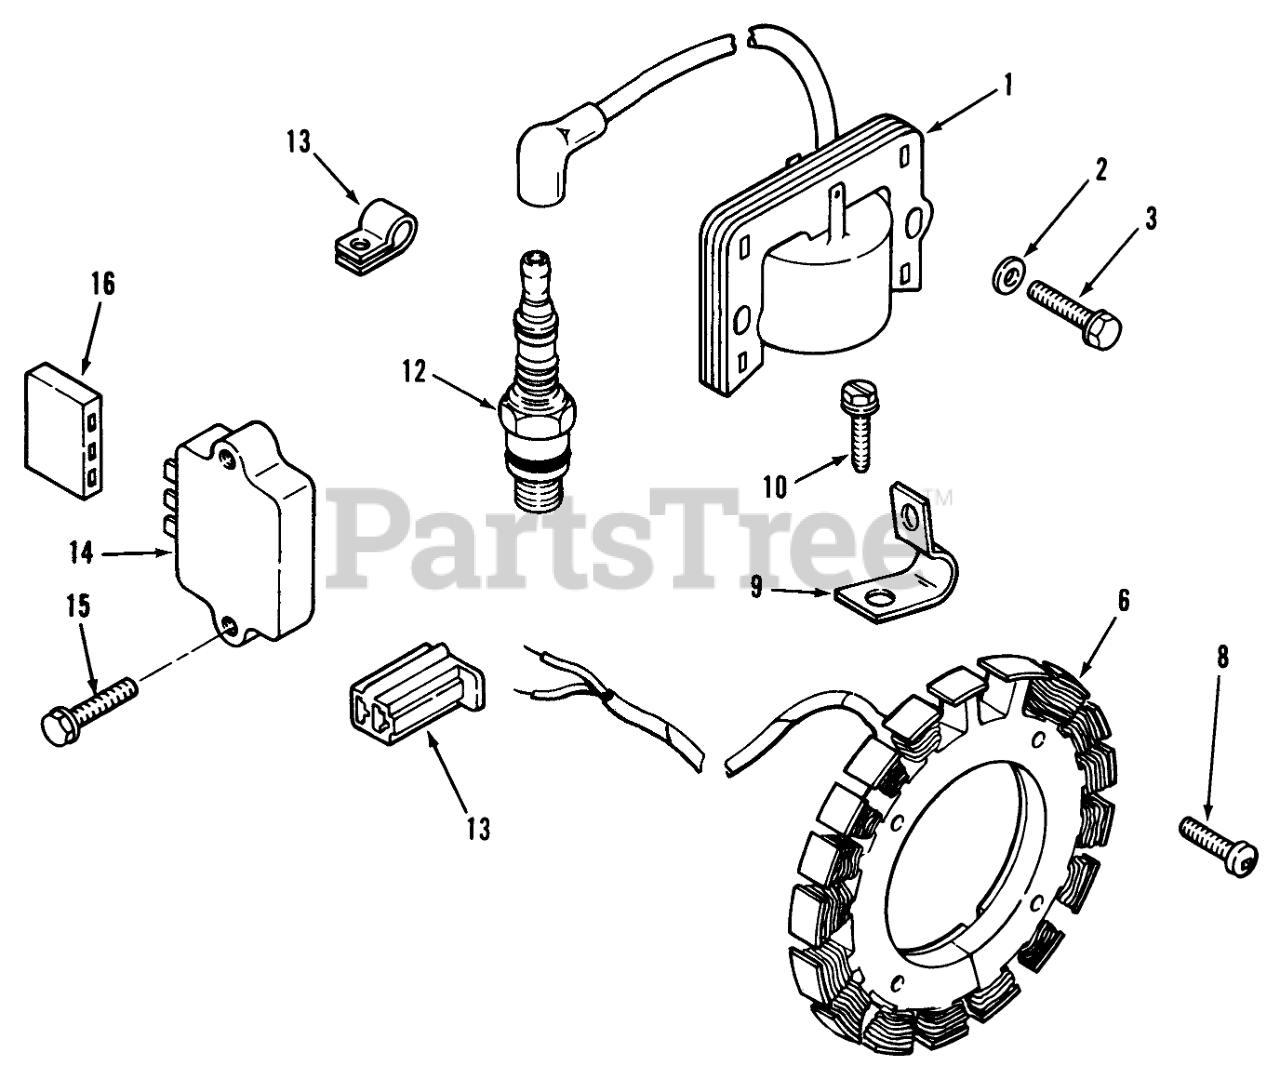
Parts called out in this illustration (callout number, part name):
1	KOHLER 47-584-02
2	KOHLER X-25-79
3	KOHLER X-156-1
6	KOHLER 237878
8	KOHLER X-67-51
9	KOHLER X-728-1
10	KOHLER X-67-59
12	KOHLER 235041-5
13	KOHLER 210281
14	KOHLER 41-403-05
15	KOHLER X-132-4
16	KOHLER 236602
